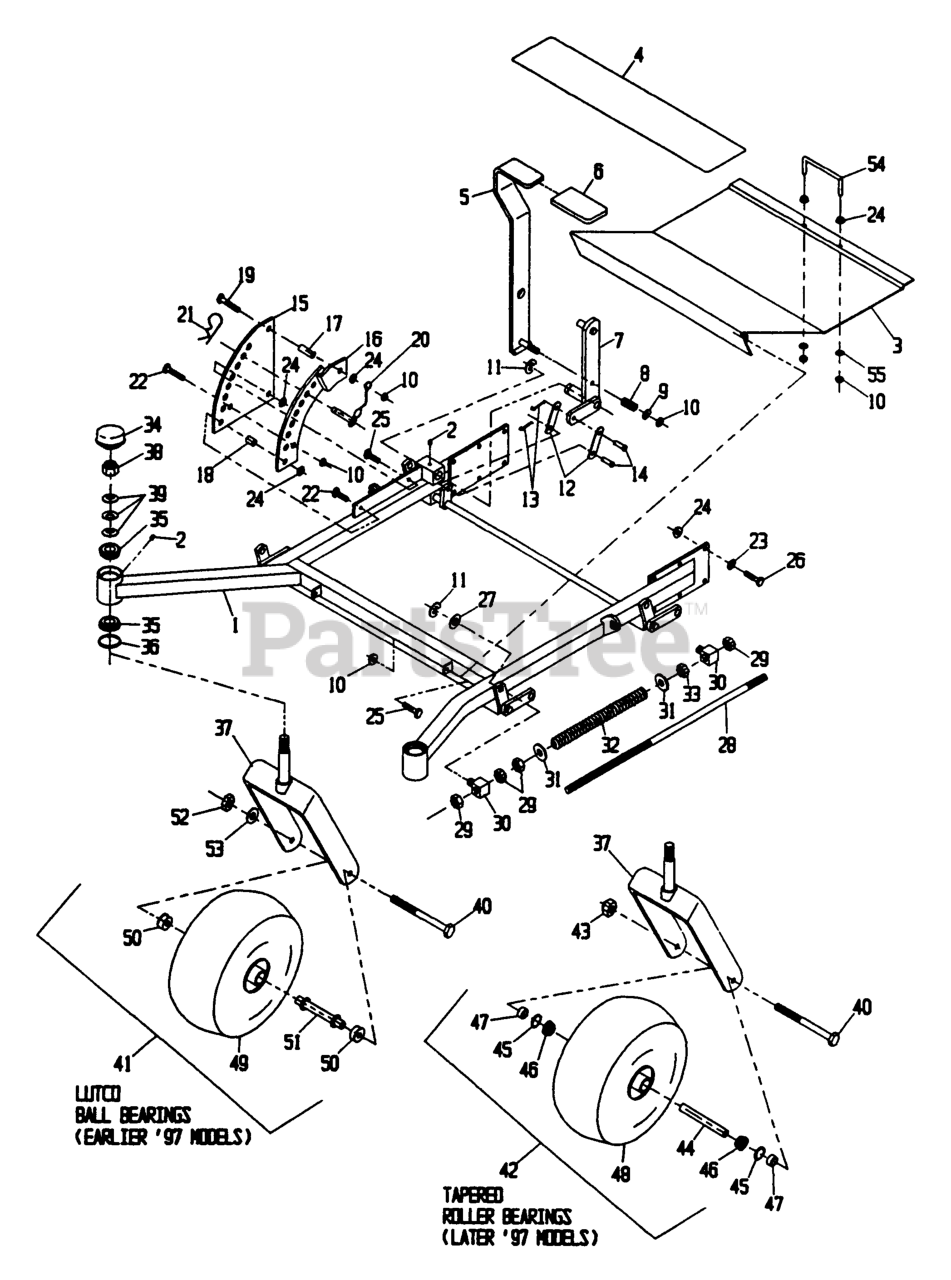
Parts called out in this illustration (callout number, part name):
4	PAD-ANTISKID
6	GRIP-LEVER, LIFT
8	SPRING-COMPRESSION
12	ARM-LIFT, DECK
14	PIN-CLEVIS
17	BUSHING-LEVER, LIFT
18	BUSHING-LEVER, LIFT
20	PIN-HITCH (W/LANYARD)
21	PIN-COTTER
28	ROD-LIFT, DECK
30	SWIVEL-DECK MOUNT, REAR
32	SPRING-SUPPORT, DECK
34	CAP-GREASE
35	Cone-Bearing Tapered Roller
36	SEAL-GREASE
39	WASHER-BELLVILLE
44	SPACER-CASTER, FRONT
45	SEAL-BEARING
46	BEARING-CONE, TAPERED ROLLER
47	SPACER-BEARING
48	WHEEL AND TIRE ASM
51	SPACER WLDMT-WHEEL
54	HANDLE,DECK
